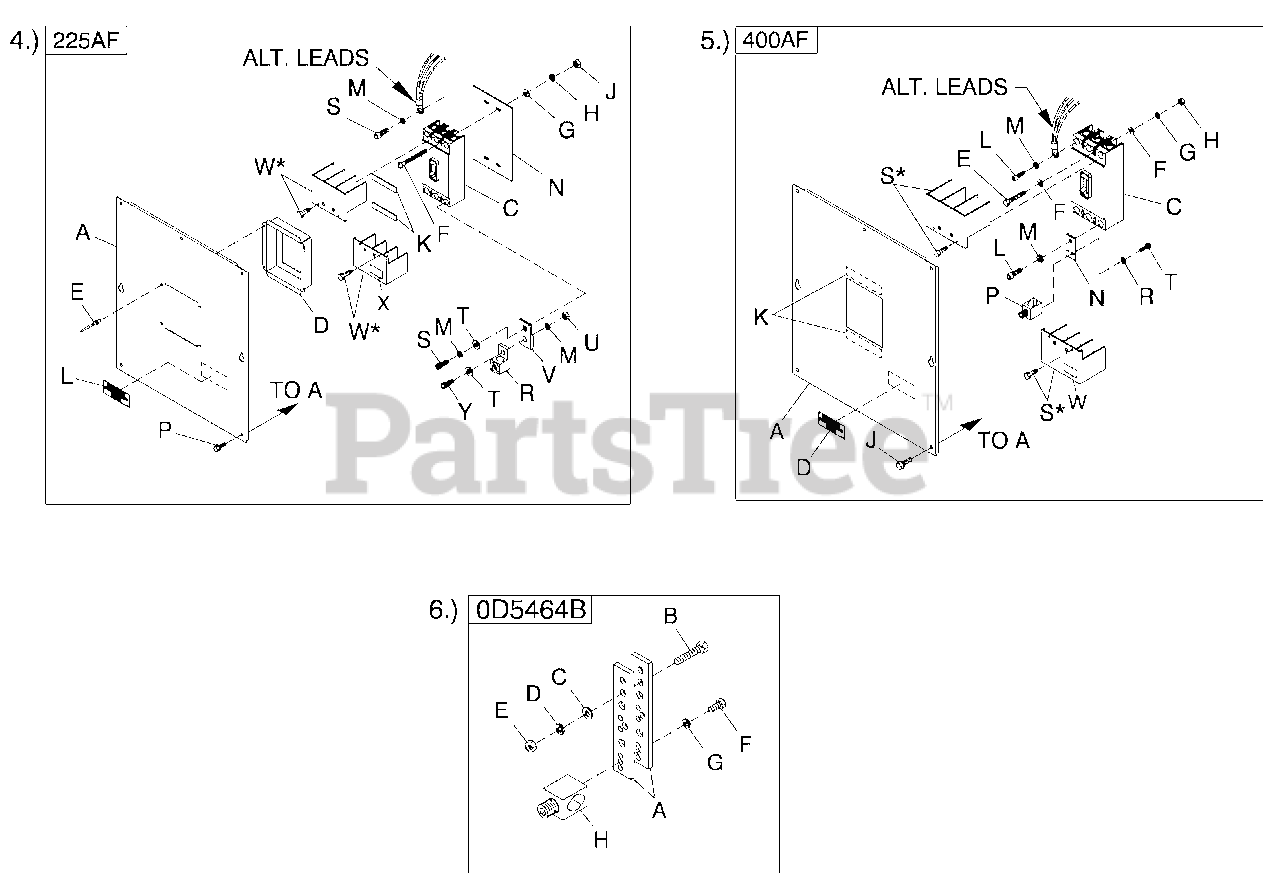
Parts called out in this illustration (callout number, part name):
A	COVER CB C3 225AF
C	CIRCUIT BREAKERS 200A FRAME
D	COVER CB DISH 225AF
E	RIVET POP .125 X .275 SS
F	SCREW RHM #8-32X3-1/4
G	WASHER FLAT #8 ZINC
H	WASHER LOCK #8-M4
J	NUT HEX #8-32 STEEL
K	TAPE ELEC 1/2 FOAM
L	DECAL CUSTOMER CONNECT INSIDE
M	WASHER LOCK M8-5/16
N	INSULATOR CB 225AF
P	SCREW THF M6-1 X 16 N WA Z/JS
R	LUG SLDLSS 300 MCM-6 AL/CU
S	SCREW SHCM8-1.25X 20 G8
T	WASHER FLAT 5/16-M8 ZINC
U	NUT HEXM8-1.25G8 CLEAR ZINC
V	BUS BAR 200A LUG ADAPTOR
W	TERMINAL COVER CB
X	DECAL TERMINAL SHOCK HZD BI
Y	SCREW SHC M8-1.25 X 25 G12.9
A	COVER CB C3 400AF
C	CIRCUIT BREAKERS 400A FRAME
D	DECAL CUSTOMER CONNECT INSIDE
E	SCREW RHM 10-32X4
F	WASHER FLAT #10 ZINC
G	WASHER LOCK #10
H	NUT HEX #10-32 STEEL
J	SCREW THF M6-1 X 16 N WA Z/JS
L	SCREW SHC M10-1.5 X 25 G12.9
M	WASHER LOCK M10
N	BUS BAR CB ADAPTER 225-400 A
P	LUG SLDLSS 600/250-1/0 X 1/4-28
R	WASHER FLAT 3/8-M10 ZINC
S	TERM COVER CB
T	SCREW HHC 1/4-28 X 1/2 G5
U	SCREW SHC M10-1.5 X 25 G12.9
V	WASHER LOCK M10
W	DECAL TERMINAL SHOCK HZD BI
A	BUS BAR NEUTRAL BLOCK 390
B	SCREW HHC M8-1.25 X 45 G8.8 FT
C	WASHER FLAT 5/16-M8 ZINC
D	WASHER LOCK M8-5/16
E	NUT HEXM8-1.25G8YEL CHR
F	SCREW HHC 1/4-28 X 3/4 G5
G	WASHER LOCK M6-1/4
H	LUG SLDLSS 600/250-1/0X1/4-28
